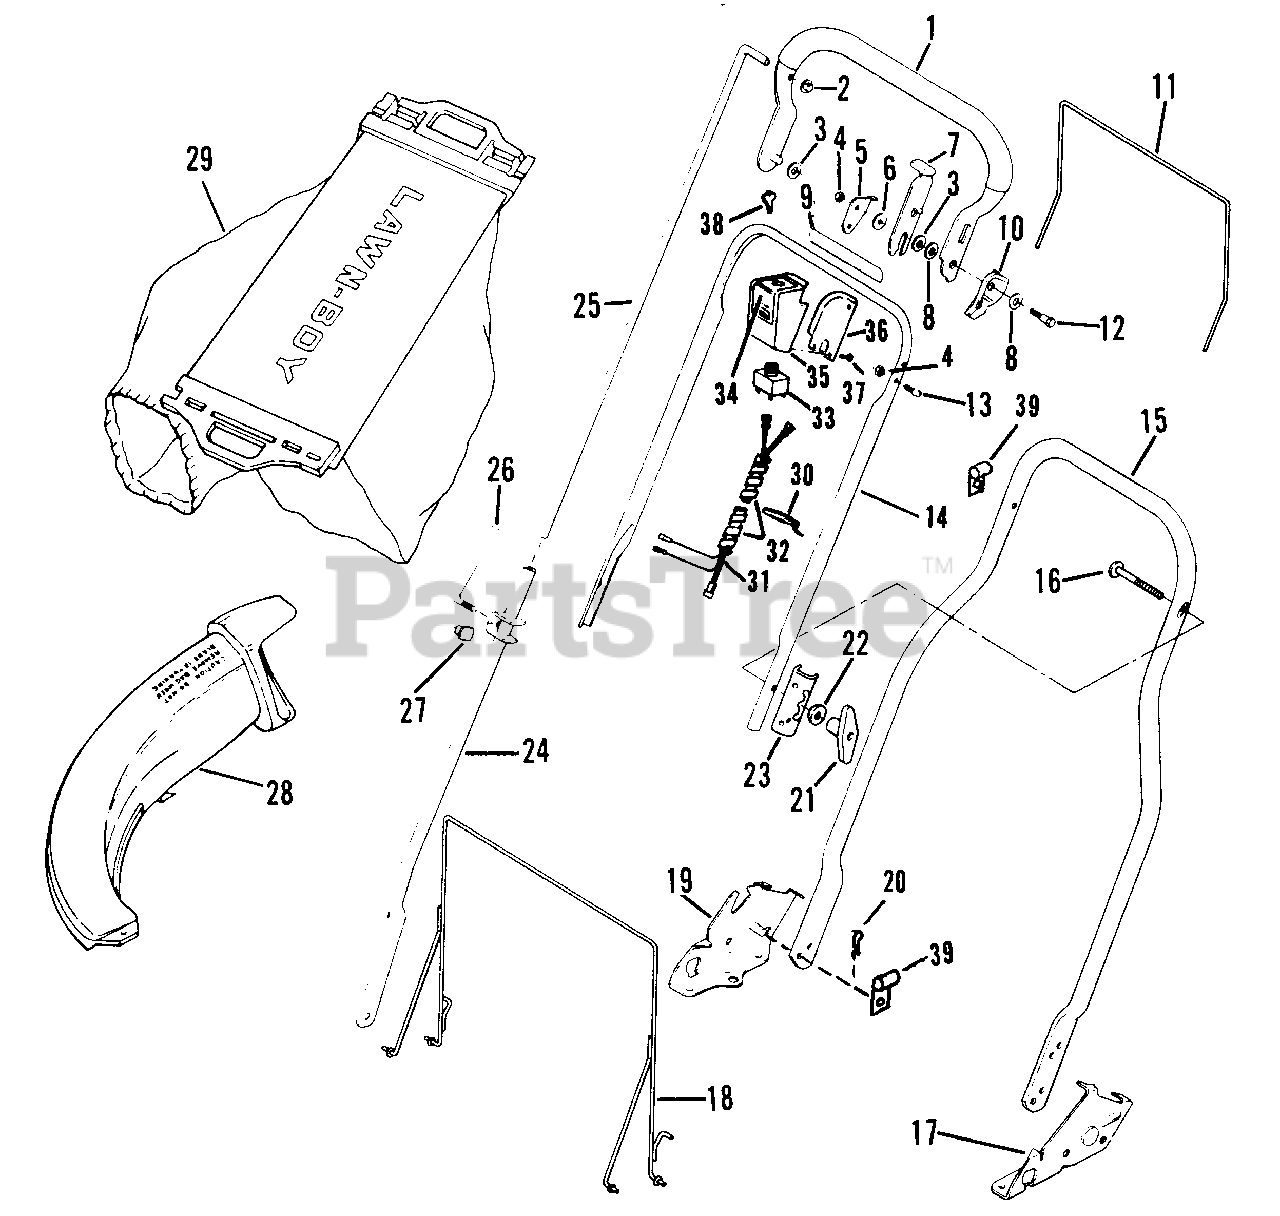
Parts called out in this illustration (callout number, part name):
1	Handle & Grip Assembly
2	Nut
3	Washer
4	Nut-Lock
5	Stop-Handle
6	Washer
7	Lever-Lockout
8	Washer
9	Decal
10	Guard-Lever
11	Hanger-Rear
12	Bolt-Shoulder
13	Screw-Stop
14	Handle-Center
15	Handle Section-Bottom
16	Screw
17	Bracket-Handle-L.H.
18	Hanger Assembly-Front
19	Bracket-Handle-R.H.
20	Hair Pin
21	Knob
22	Washer-Curved
23	Bracket-Rear Hanger
24	Control Lever Assembly
25	Control Rod
26	Screw
27	Nut
28	Chute Assembly
29	Bag & Support Assembly
30	Cable Tie
31	Wire Harness Assembly-Switch
32	Spiral Tubing
33	Key Switch
34	Decal-Switch
35	Housing-Switch
36	Retaining Plate-Switch Housing
37	Screw
38	Key-Switch
39	Clamp
